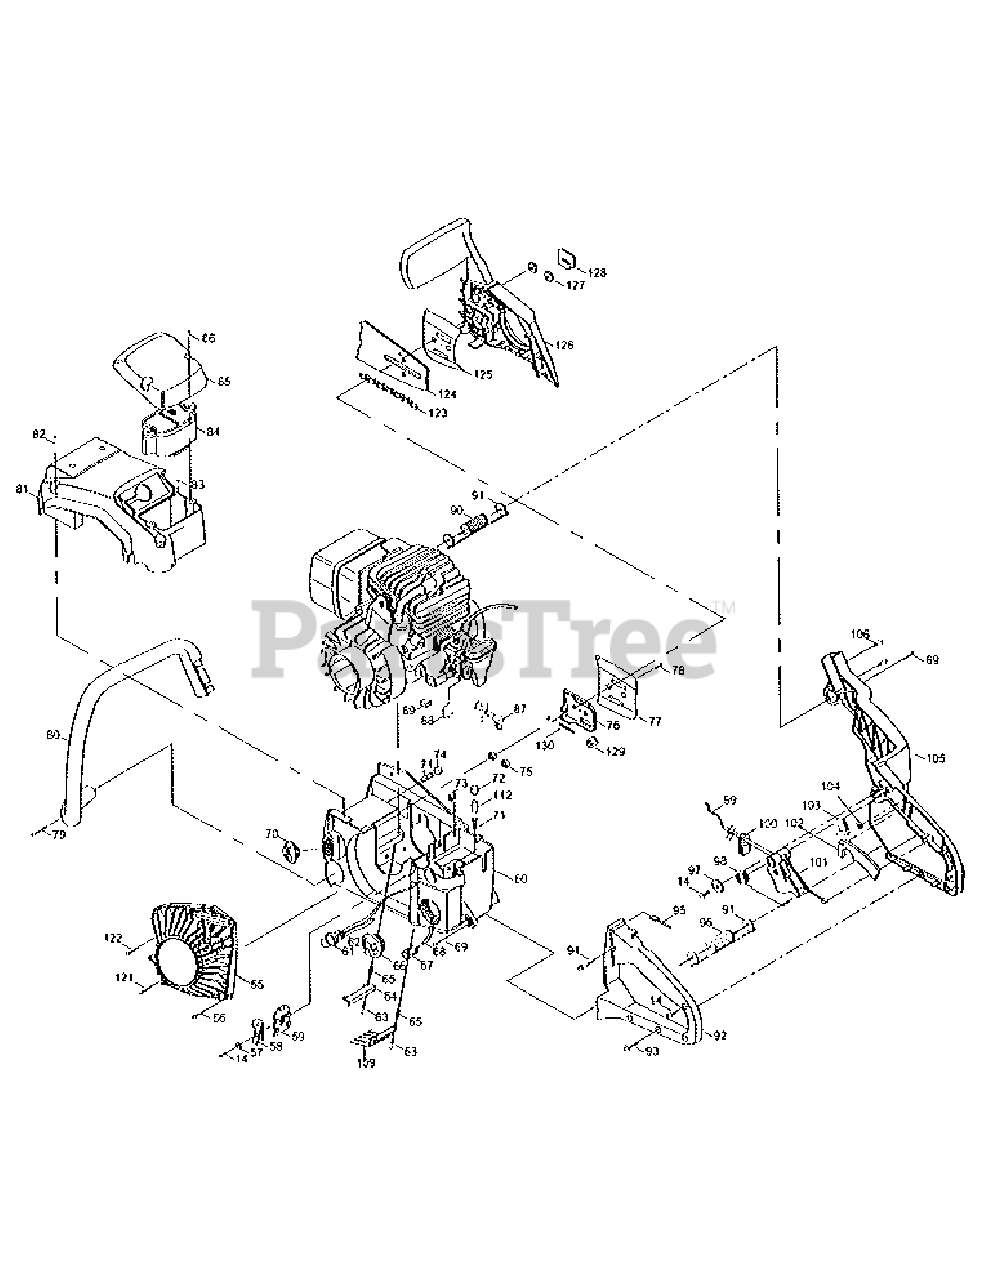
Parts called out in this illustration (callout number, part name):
7	CRANKCASE LOWER
9	C'SHAFT/C'ROD ASS'Y
12	PUMP ASS'Y
13	CONNECTOR
15	FITTING, PULSE LINE
16	CRANKCASE UPPER
18	CLAMP, WIRE HOSE
19	CONDUIT, FLEX
23	RING, PISTON
25	SPARK PLUG
26	SCREW
29	IGNITION ASS'Y
31	CONTACT, CROUNT
36	MUFFLER BODY ASS'Y
37	SCREW
41	COVER, MUFFLER
42	LOCKPLATE
55	STARTER ASS'Y
58	METAL CLIP
60	FUEL/OIL TANK ASS'Y
61	PRIMER, PREMOTE
66	CAP, FUEL
67	FILTER, FUEL
70	BOOT, CARB
71	VALVE DUCKBILL
76	PLATE, BAR
77	PLATE, FLANGE
80	HANDLE ASS'Y
81	COVER ASS'Y
83	SCREW
84	AIR CLEANER ASS'Y
87	CHOKE ASS'Y
88	ROD, CHOKE
90	ISOLATOR ASS'Y
91	CABLE ASS'Y
92	COVER ASS'Y HANDLE
96	ISOLATOR ASS'Y
102	RELEASE TRIGGER
103	LATCH, HIGH IDLE
105	FRAME, REAR
113	GEAR, WORM
117	DRUM SPRKT ASS'Y
118	CLUTCH ASS'Y
120	BOOT, CARB
122	SCREW
123	18 INCH CHAIN
123	20 INCH CHAIN
124	18 INCH BAR
124	20 INCH BAR
126	CHAIN BRAKE ASS'Y
132	CARRY CASE
